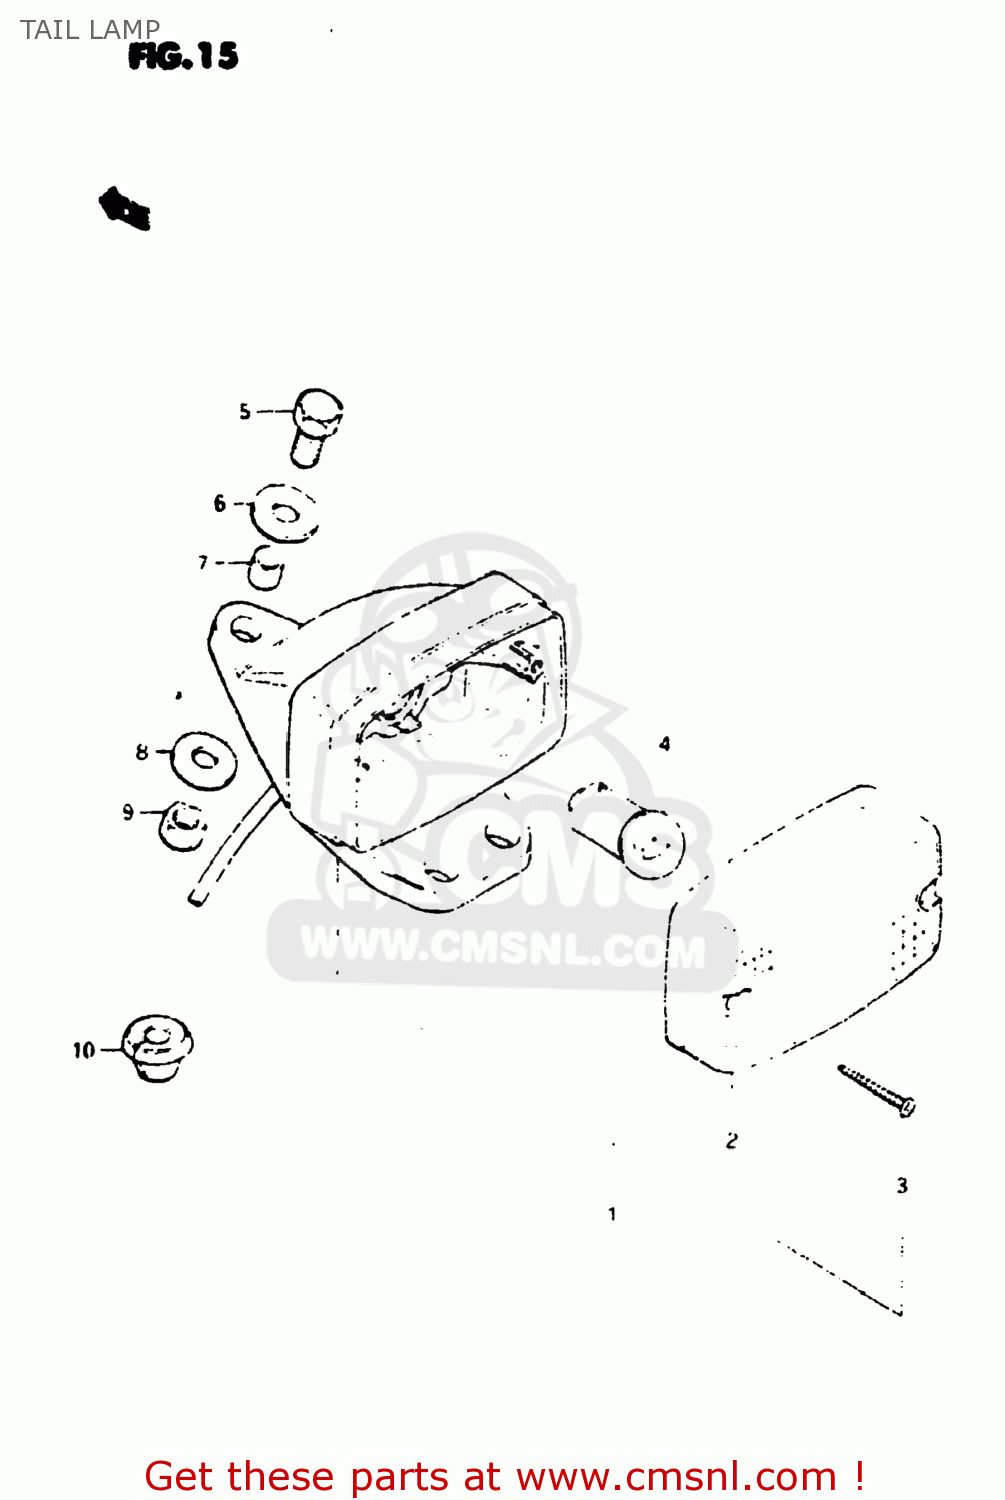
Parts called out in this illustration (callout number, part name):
1	LAMP ASSEMBLY,REAR COMBINATION
2	LENS
3	SCREW
4	BULB(6V5W,TOKAI DENSO)
5	BOLT
6	WASHER (6.5X20X1.2)
7	SPACER (6.1X9X9)
8	WASHER
9	NUT
10	GROMMET
